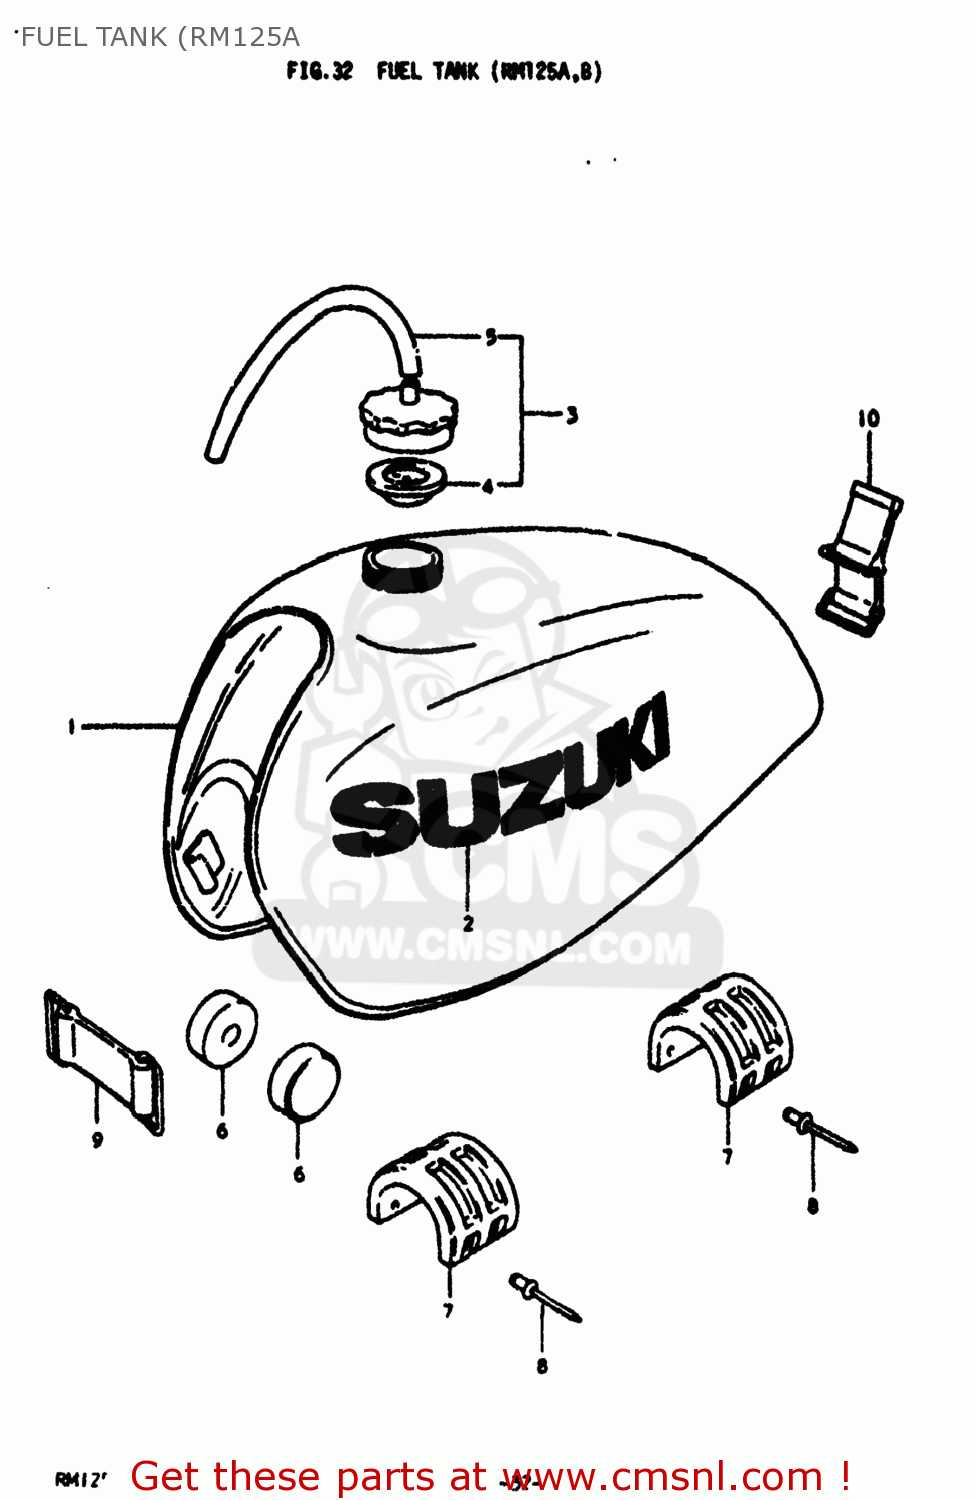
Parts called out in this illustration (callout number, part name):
1	TANK ASSEMBLY,FUEL
2	EMBLEM
3	CAP ASSY,FUEL TANK FILLER
4	GASKET,FUEL TANK CAP (NAS)
5	HOSE
6	CUSHION
7	CUSHION,FUEL TANK,CENTER
8	RIVET
9	BAND
10	BAND
